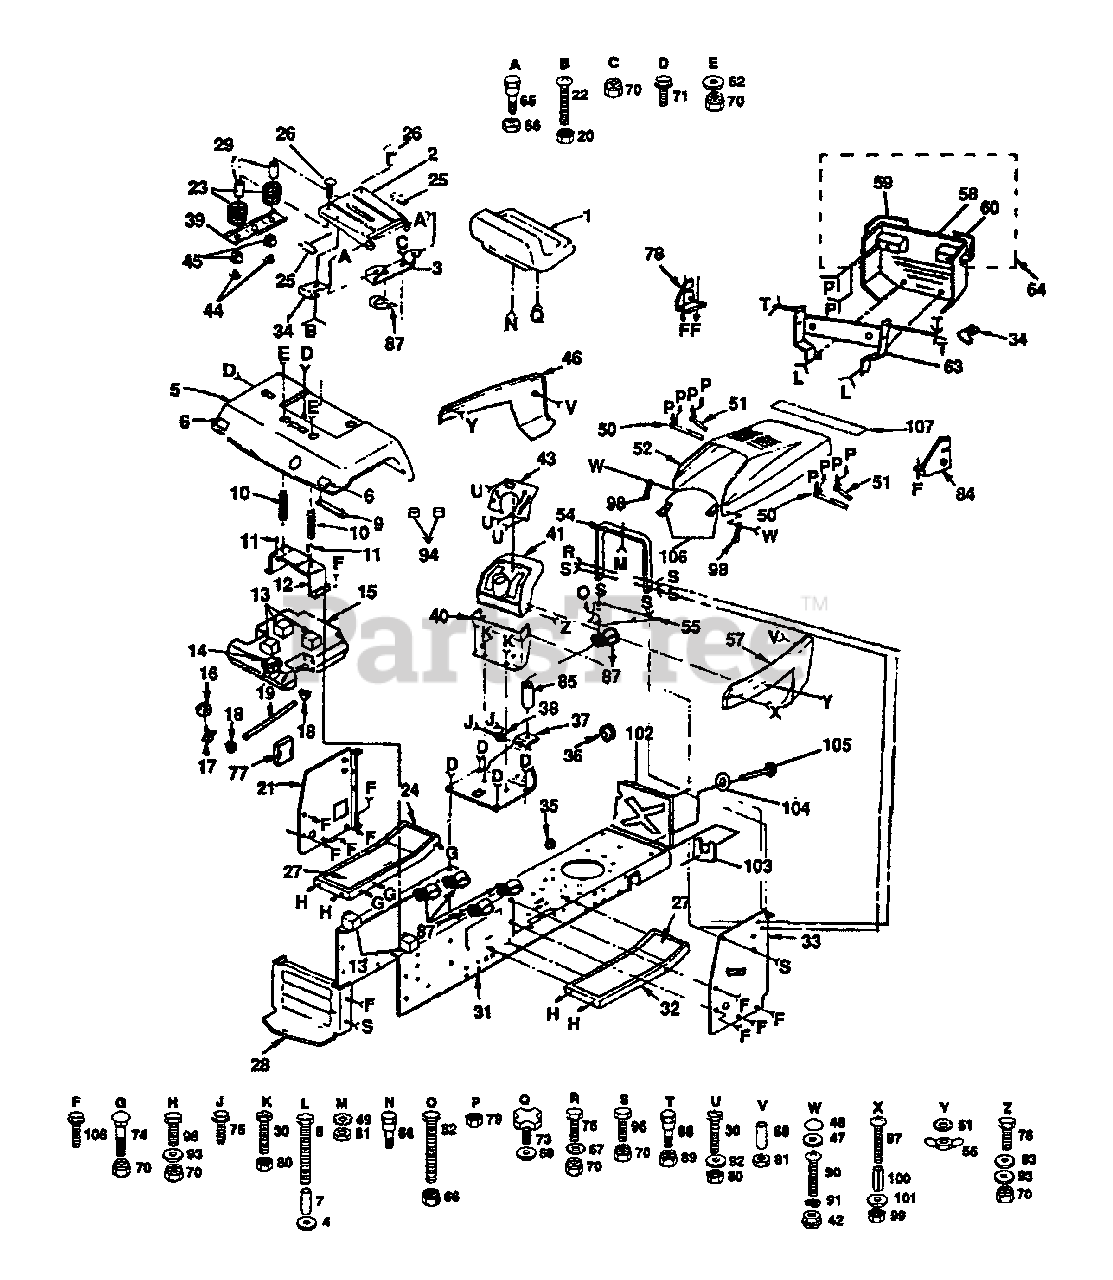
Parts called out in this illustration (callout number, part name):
1	Seat
3	Bracket, Pivot, Seat
4	Washer 9/32 x 3/4 x 16 Ga.
6	Reflector, Taillight
8	Bolt, Fin, Hex 1/4-20 x 2-1/2
9	Strap, Fender
10	Spring, Compression, Seat
12	Bracket, Fender
13	Pad, Spacer
15	Tank, Fuel
16	Bushing
17	Stem, Tank, Fuel
18	Clamp, Hose
19	Line, Fuel
20	Nut, Keps #10
21	Panel, Dash, LH.
22	Screw, Pan Hd. #10-32
23	Spring, Compression
24	Footrest, L.H.
25	Foam, Strip
26	Bolt, Carriage 1/4-20 x 1-1/4
27	Pad, Footrest
29	Spacer, Split
30	Screw, Mach. Cr. Thd. 5/16-18 x 3/4
32	Footrest, R.H.
33	Panel, Dash, R.H.
34	Clip, Insulated
35	Grommet, Split
37	Saddle
38	Bushing, Steering
39	Bracket, Switch Mount
40	Assembly, Dash, Lower
41	Dash
42	Nut, Weld
43	Plate, Dash
44	Locknut, Flange Hex, Large
45	Bushing, Snap
46	Panel, Side, LH.
47	Washer, Cap, Snap
49	Washer, Lock, Tooth External 1/4
50	Assembly, Strap Hinge, Rear
51	Assembly, Strap Hinge, Front
52	Hood
54	Support, Dash
55	Plate, Support, Battery
56	Nut, Wing
57	Panel, Side, R.H.
58	Grill
59	Lens, LH.
60	Lens, R.H.
61	Washer, Lock Tooth Intl External 1/4
62	Washer 13/32 x 1 x 14 Gauge
63	Support, Grill, Assembly
64	Assembly, Grill
65	Bolt, Shoulder 5/16-18
66	Nut, Crownlock 5/16-18
67	Washer, Lock Tooth External 3/8
69	Washer 17/32 x 1-3/16 x 12 Gauge
70	Nut, Crownlock 3/8-16
71	Screw, Hex Washer Thread Rolling 3/8-16 x 1/2
73	Knob, 1/2" Seat
74	Bolt, Carriage 3/8-16 x 3/4
75	Screw, Hex Self Tapping #10-16 x 1/2
76	Bolt, Hex 3/8-16 x 1
77	Cover, Access
78	Bracket Assembly, L.H.
79	Nut, Keps, Hex 1/4-20 UNC
80	Nut, Keps, 5/16-18 UNC
81	Nut, Fin, Hex 1/4-20 UNC
82	Bolt, Hex 5/16-18 x 2
84	Bracket, Assembly R.H.
86	Bolt, Shoulder 5/16-18 x .62
87	Clip
88	Bolt, Shoulder 1/4-20
89	Nut, Crownlock 1/4-20
90	Screw, Pan Hd. Mach. #10-24 x 1/2
91	Washer, Lock #10
92	Washer 11/32 x 11/16 x 16 Gauge
93	Washer 13/32 x 13/16 x 12 Gauge
94	Cap, Spring, Seat
96	Bolt, Hex 3/8-16 x 3/4
97	Screw, Mach. Cr, Pan #10-24 x 1-1/4
98	Latch, Hood
99	Nut, Keps #10-24
100	Spacer, Split #10 x 3/4
101	Washer 7/32 x 1/2 x 18 Gauge
102	Shield, Heat
103	Receptacle, 1/4 Turn
104	Retainer, 1/4 Turn
105	Stud, 1/4 Turn
106	Baffle, Vertical
107	Foam, Strip 18"
108	Screw, Hex Washer, Thread Rolling 3/8-16 x 3/4
